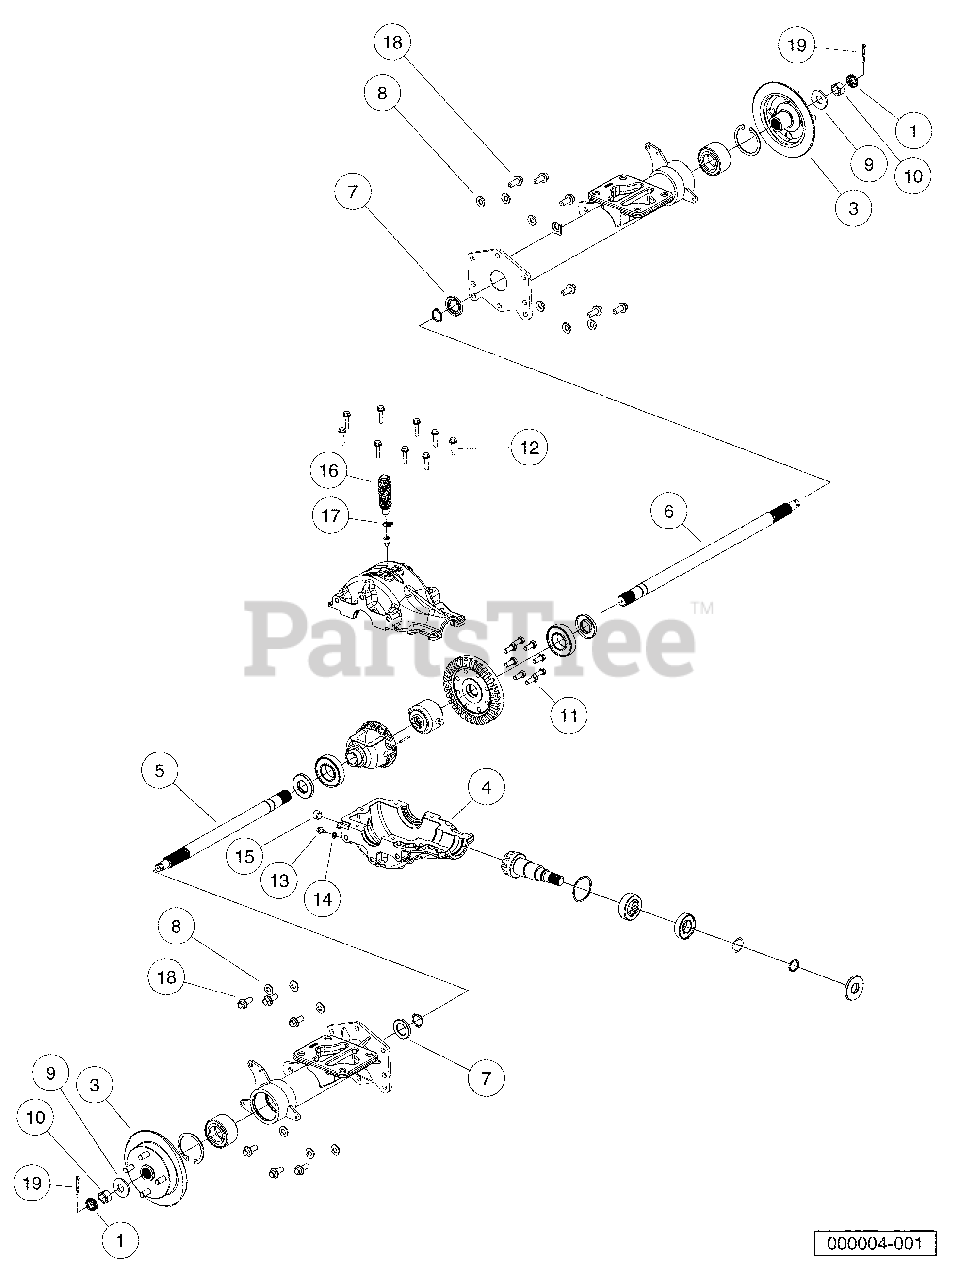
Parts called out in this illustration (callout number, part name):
1	Axle, Rear, Guard Mounts
2	Locking Cap, Nut
3	Assy, Rotor, Brake, Rear
4	Gearcase, Lower, Machined
5	Axle, Right-hand
6	Axle, Left-Hand
7	Washer,counterbored 51 X 30
8	Washer, Bellevle, 1.063 X .043
9	Washer, Belleville, 49 X 4
10	Nut, Hex, M20 X 1.5 , Modified
11	Screw, M10 X 25
12	Screw,hex Flange, M8 X 35
13	Plug,3/8-16, Hex Flange
14	Washer, .625 X .382 X .60
15	Plug, Square Skt, 1/12-14, Ptf
16	Bellows, Vent, Upper Housing
17	Clamp, Hose, Dw-9.5
18	Screw, Hex Fl, M12 X 1.75 X 30
19	Pin, Cotter, 5/32 X 1.25
